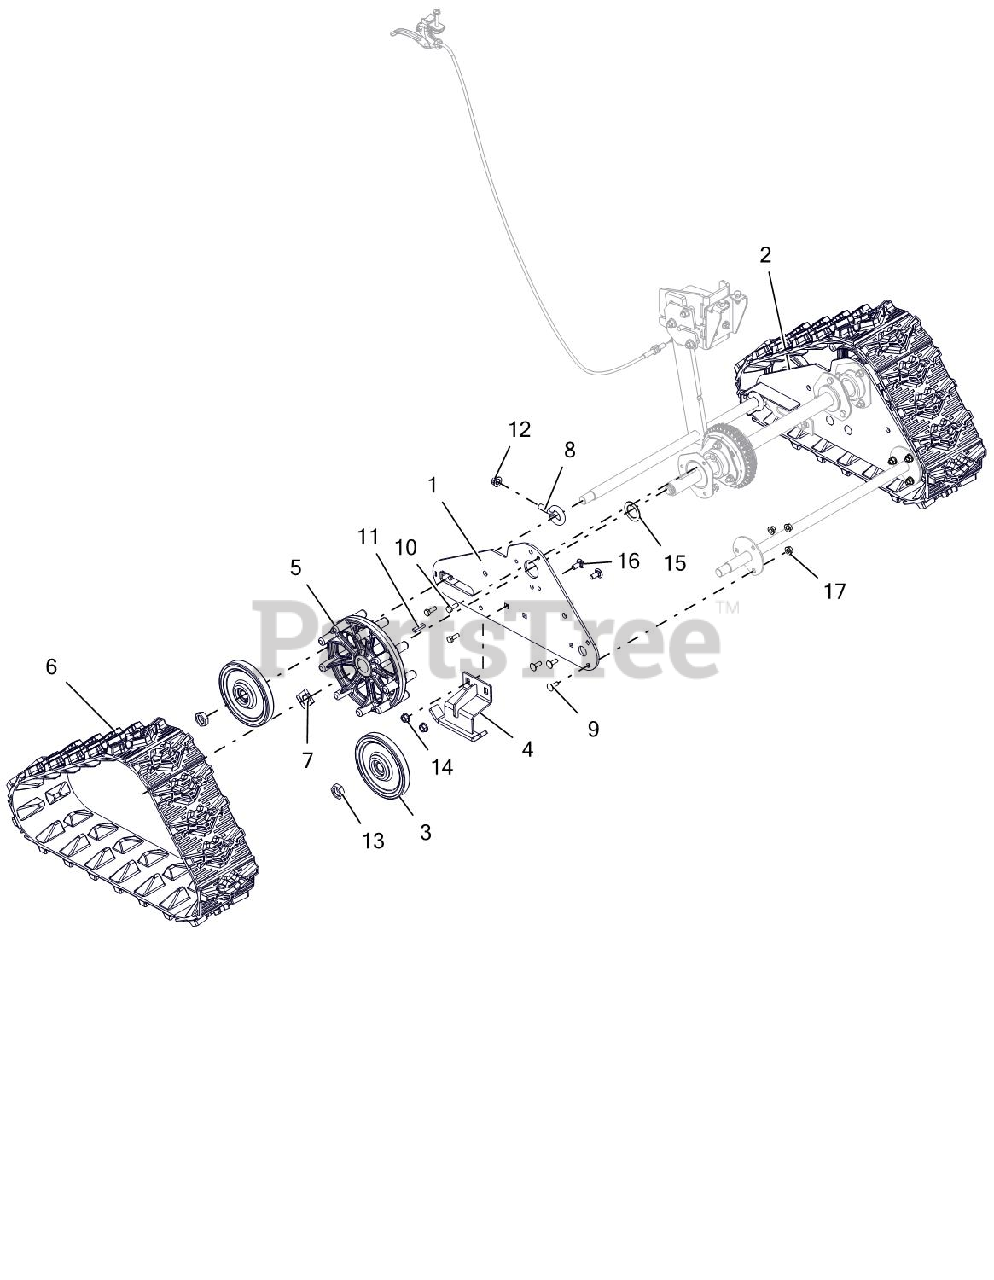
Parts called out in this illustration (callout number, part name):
1	SIDE PLATE, RH-TRACK
2	SIDE PLATE, LH-TRACK
3	WHEEL, BOGIE - SINGLE BEARING
4	RUNNER, GUIDE-TRACK
5	WHEEL, MACHINED DRIVE
6	TRACK, RUBBER
7	CLIP, SNAP .625 DIA
8	BLT-EYE .375-16X.880 YWZC
9	@BLT-RDHDSQNK .25-20X.75 G5YZ
10	@BLT-HEX .25-20X.75 GR5 YWZC
11	KEY-RECT .25X.188X1.00
12	NUT-LK-CTR-FLG .38-16 YWZC
13	@NUT-LK-NYL .625-18 YWZC
14	@NUT-LK-TOP-FLG .31-18 YWZC
15	WSHR-FL-STL 1.010X1.505X.062YZ
16	@BLT-RDHDSQNK .31-18X.75 G5YZ
17	@NUT-LK-TOP-FLG .25-20 YWZC
